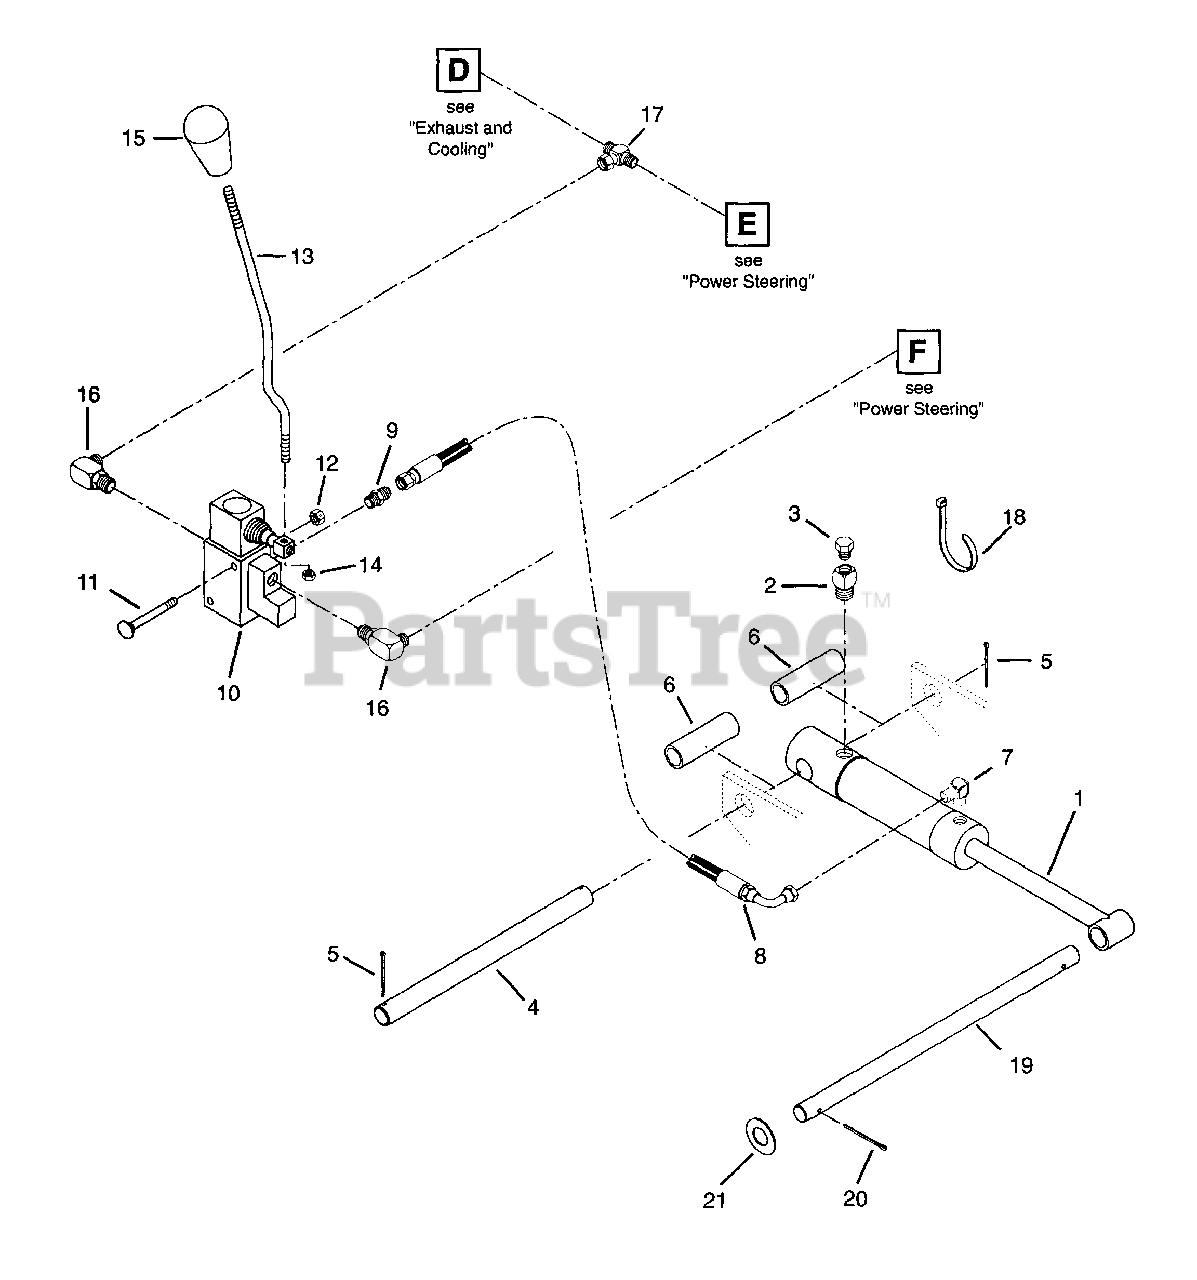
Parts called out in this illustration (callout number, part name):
1	Cylinder, Lift
2	Adapter, Fitting
3	Plug, Breather 3/8"
4	Pin-Lift Cylinder Mount
5	Pin-Cotter
6	Spacer, Lift Cylinder
6	Spacer, Lift Cylinder Long
6	Spacer, Lift Cylinder Short
7	Adapter
8	Assembly, Hydraulic Hose
9	Adapter-Pipe
11	Bolt-Round Head Square Neck .31-18 x 2.25
12	Nut-Locking .31-18
13	Control Rod
14	Nut-Jam M10-1.5
15	Knob
16	Fitting, Adapter
17	Adapter, Fitting Tee
18	Tie Wrap, Black
19	Shaft, Mower Lift
20	Pin-Cotter .25 x 2.0
21	Washer-Flat-Steel 1.38 x 2.50 x .136
